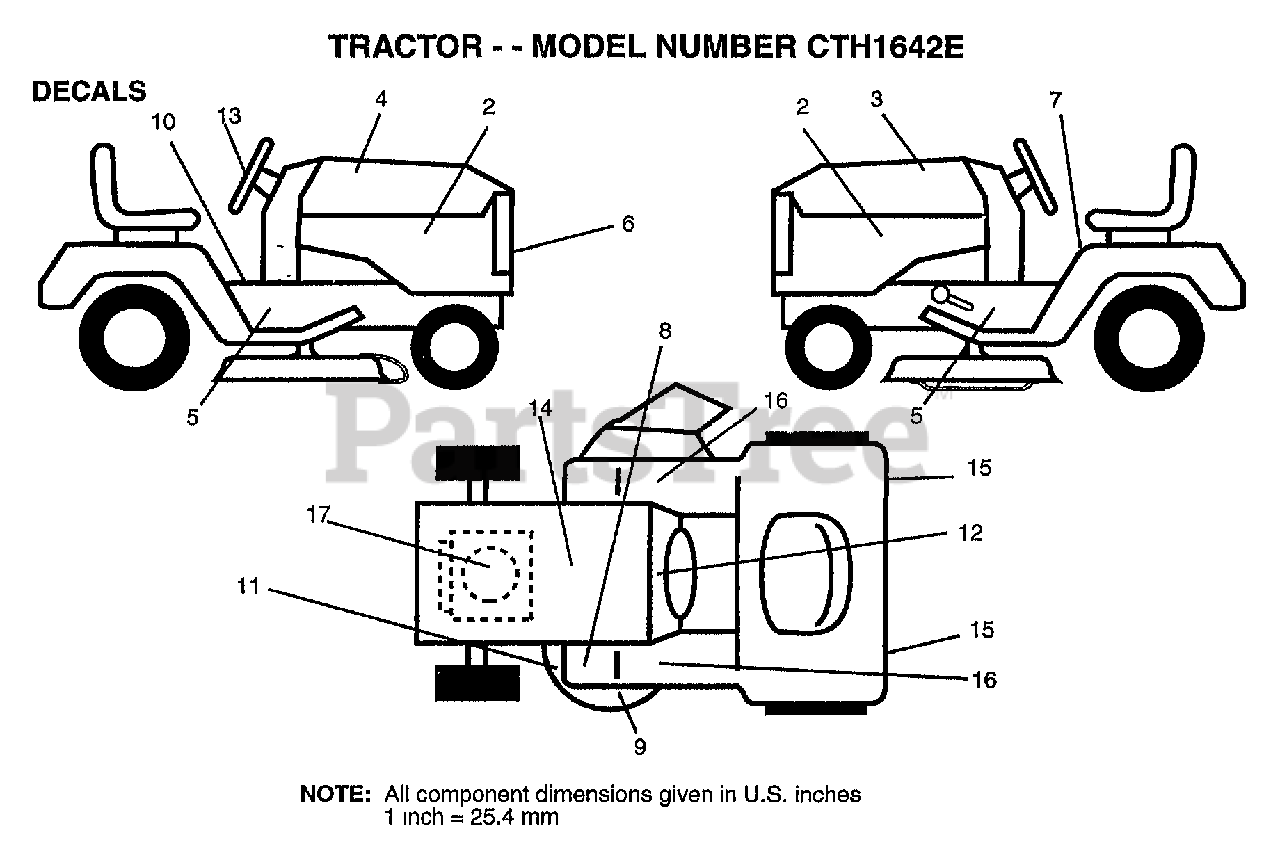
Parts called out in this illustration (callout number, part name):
2	"DECAL PANEL,SIDE"
3	DECAL.HOOD.LH
4	DECAL.HOOD.RH
5	"DECAL CHASSIS 42"""
6	DECAL GRILLE
7	"DECAL DANGER,FEND"
9	"DECAL,ENVIRO DECK"
10	DECAL BRAK PARK
11	DECAL
12	"DECAL-INST,OPER"
13	DECAL INST STG WH
14	DECAL.BATRY.3-3908
15	REFLECTOR-TAIL YT
16	FOOTREST PAD
17	DECAL, HP ENGINE
